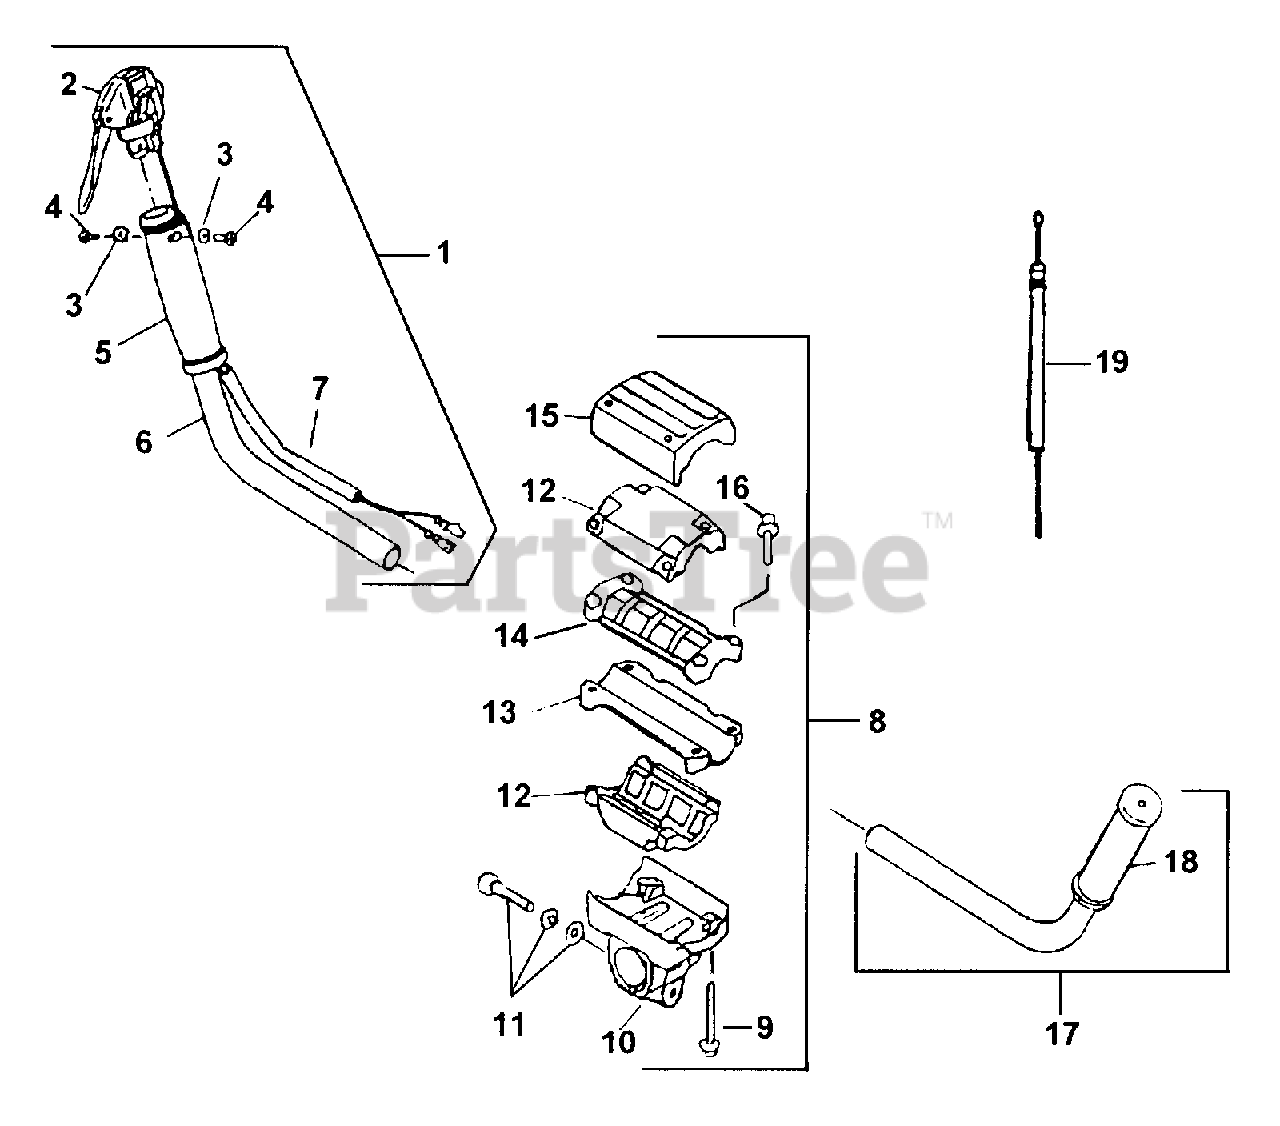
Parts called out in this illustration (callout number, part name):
1	HANDLE ASSY R. H.
2	THROTTLE ASSY.
4	SCREW
5	GRIP R.H.
6	HANDLE & GRIP R.H.
7	TUBE, HARNESS
8	HANDLE JOINT ASSY.
9	BOLT & WASHER
10	HANDLE JOINT LOWER
11	SCREW & WASHER
12	ISOLATING RUBBER
13	PIPE FITTING LOWER
14	PIPE FITTING UPPER
15	HANDLE JOINT UPPER
16	SCREW
17	HANDLE & GRIP L.H.
18	GRIP L.H.
19	THROTTLE CABLE
